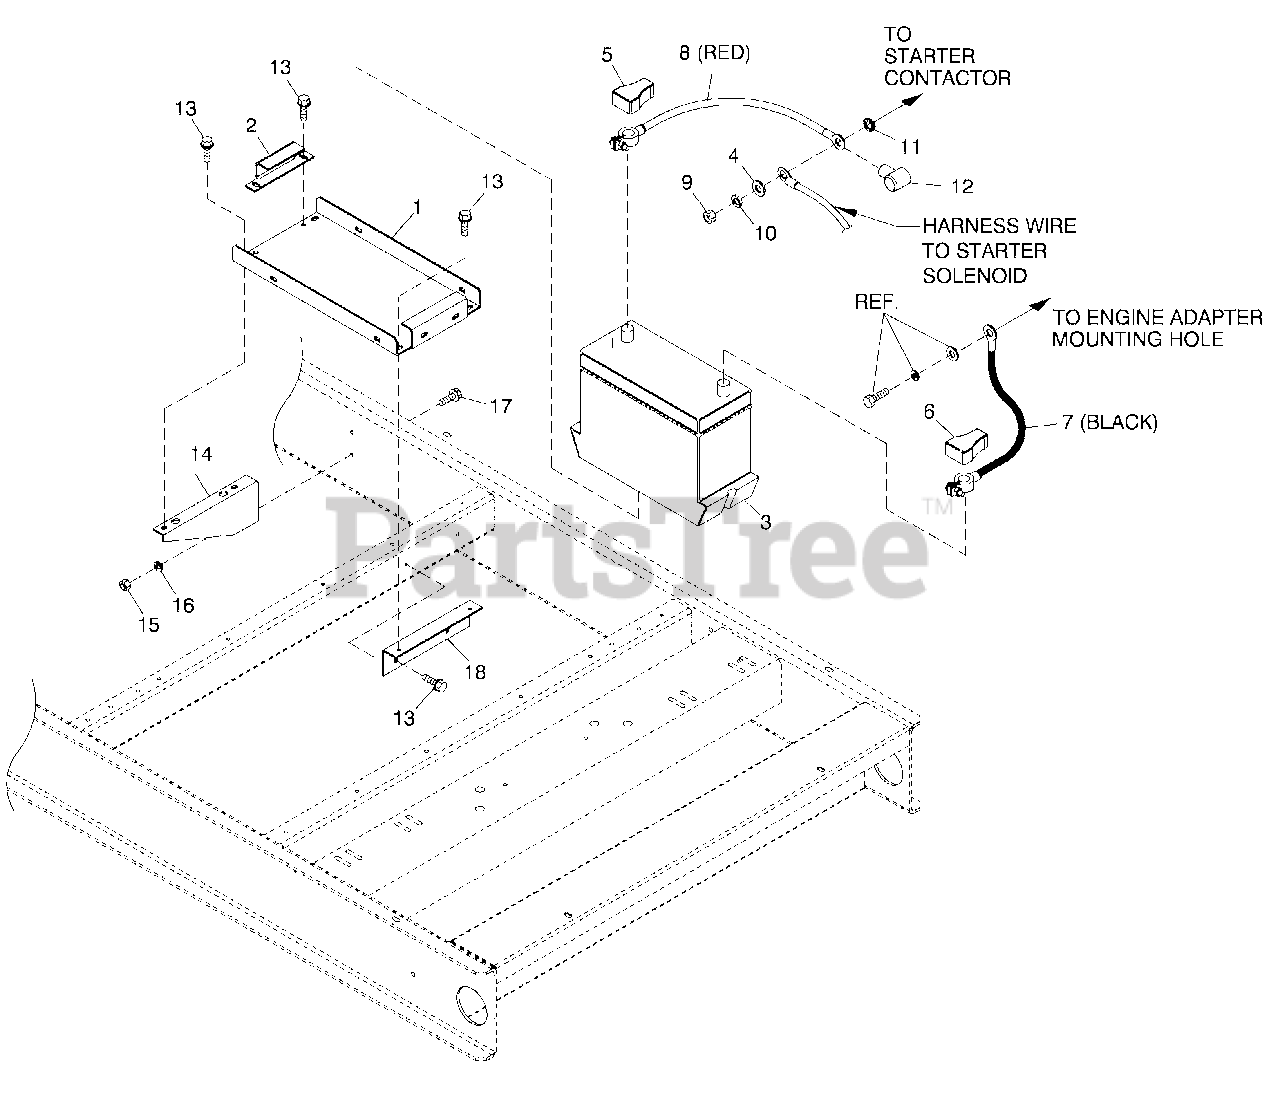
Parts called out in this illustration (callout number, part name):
1	TRAY BATTERY 27F
2	STRAP BATTERY RETAINMENT 27F
3	BATTERY 12VDC 90-AH 27F
4	WASHER FLAT 3/8-M10 ZINC
5	BATTERY POST COVER RED +
6	BATTERY POST COVER BLK -
7	CABLE BATTERY BACLK #1 X 26.00
8	CABLE BATTERY RED #1 X 28.00
9	NUTHEXM8-1.25 G8YEL CHR
10	WASHER LOCK M8-5/16
11	WASHER SHAKEPROOF EXT 5/16 STL
12	BOOT BATTERY CABLE
13	SCREW THF M6-1 X 16 N WA Z/JS
14	SUPPORT BATTERY TRAY
15	WASHER LOCK M6-1/4
16	NUT HEX M6X 1.0 G8YEL CHR
17	SCREW HHC M6-1.0X 20 G8.8
18	SUPPORT 27F BATTERY
